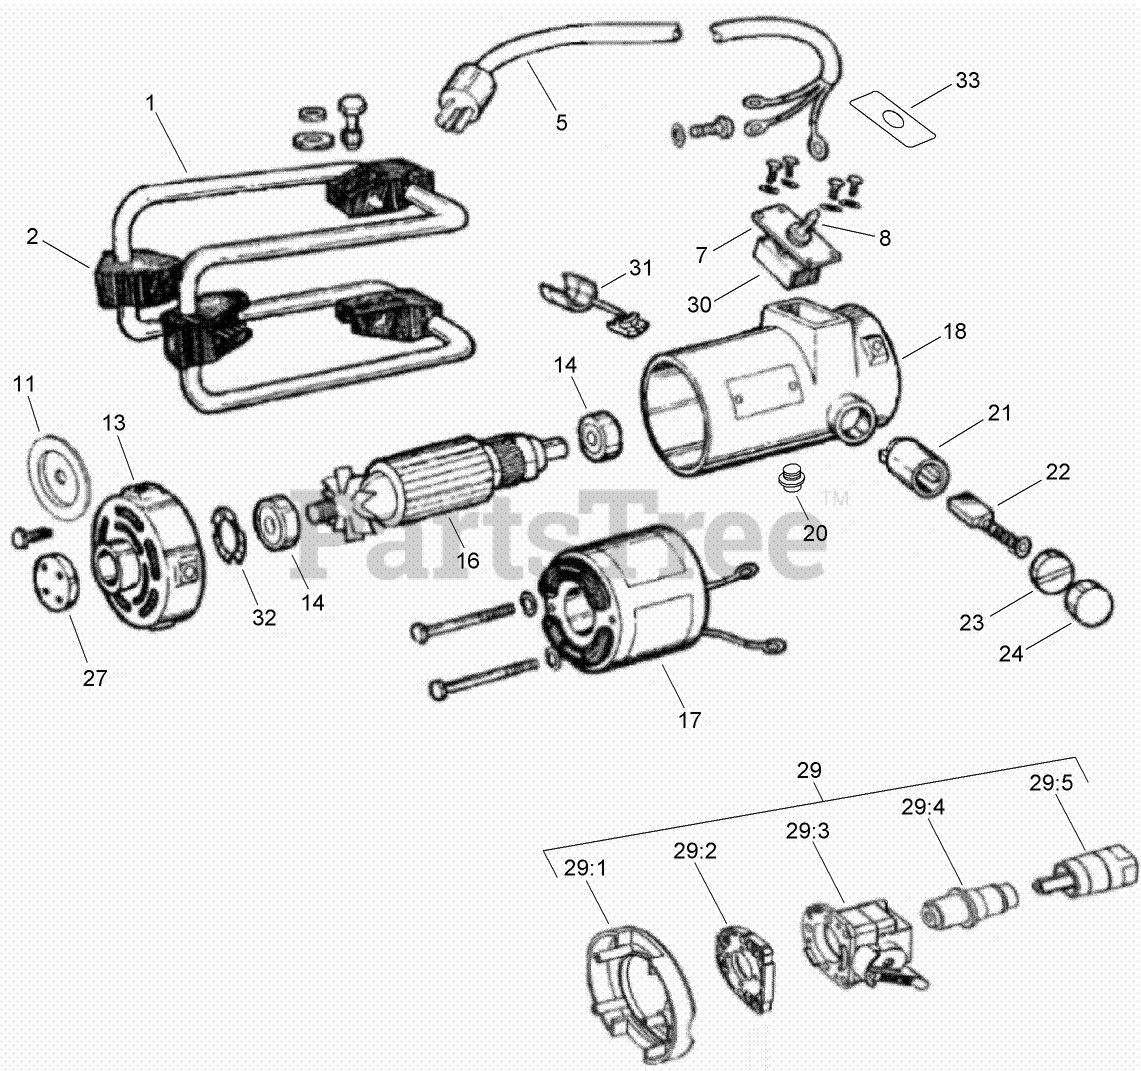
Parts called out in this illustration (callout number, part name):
1	FRAME ASM
2	MOUNT-SHOCK
5	CORD ASM
7	SWITCH PLATE ASM
8	BOOT-RUBBER, SWITCH
11	BAFFLE ASM
13	BELL-END
14	BEARING
16	ARMATURE (115V)
17	FIELD (115V)
18	HOUSING
20	PLUG-PORT, ACCESS
21	HOLDER-BRUSH
23	SCREW-CAP
24	CAP-THREADED, PROTECTIVE
29	QUICK DISCONNECT KIT
29:1	BAFFLE-RH
29:2	SPACER
29:3	CASING-ADAPTOR
29:4	CORE ADAPTOR ASM
29:5	COUPLER-SHAFT
30	KILL SWITCH ASM
31	STRAIN RELIEF ASM
32	RING-TOLERANCE
33	DECAL-SWITCH PLATE
